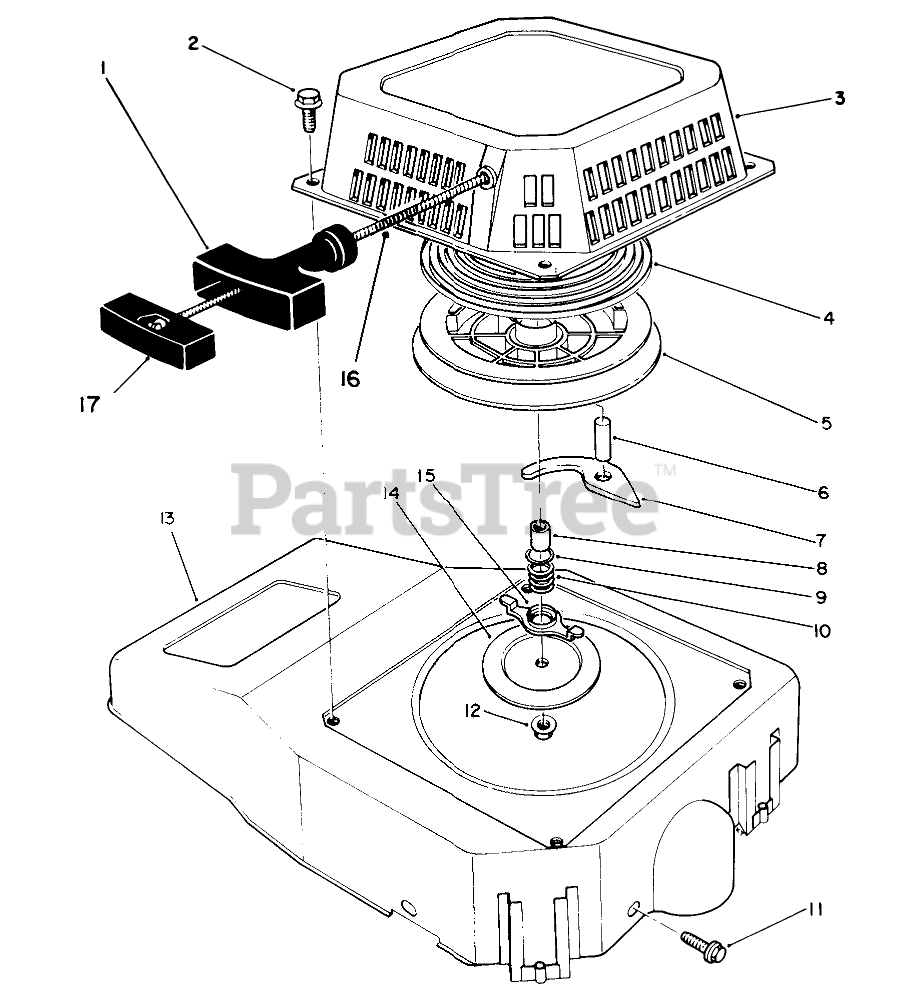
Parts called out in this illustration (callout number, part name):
1	HANDLE
2	SCREW-HHF
3	Case-Recoil
4	SPRING
8	Spacer
9	WASHER
10	Spring-Friction
13	SHROUD
14	PLATE
15	Guide-Paw
16	ROPE-STARTER
17	RETAINER HANDLE
